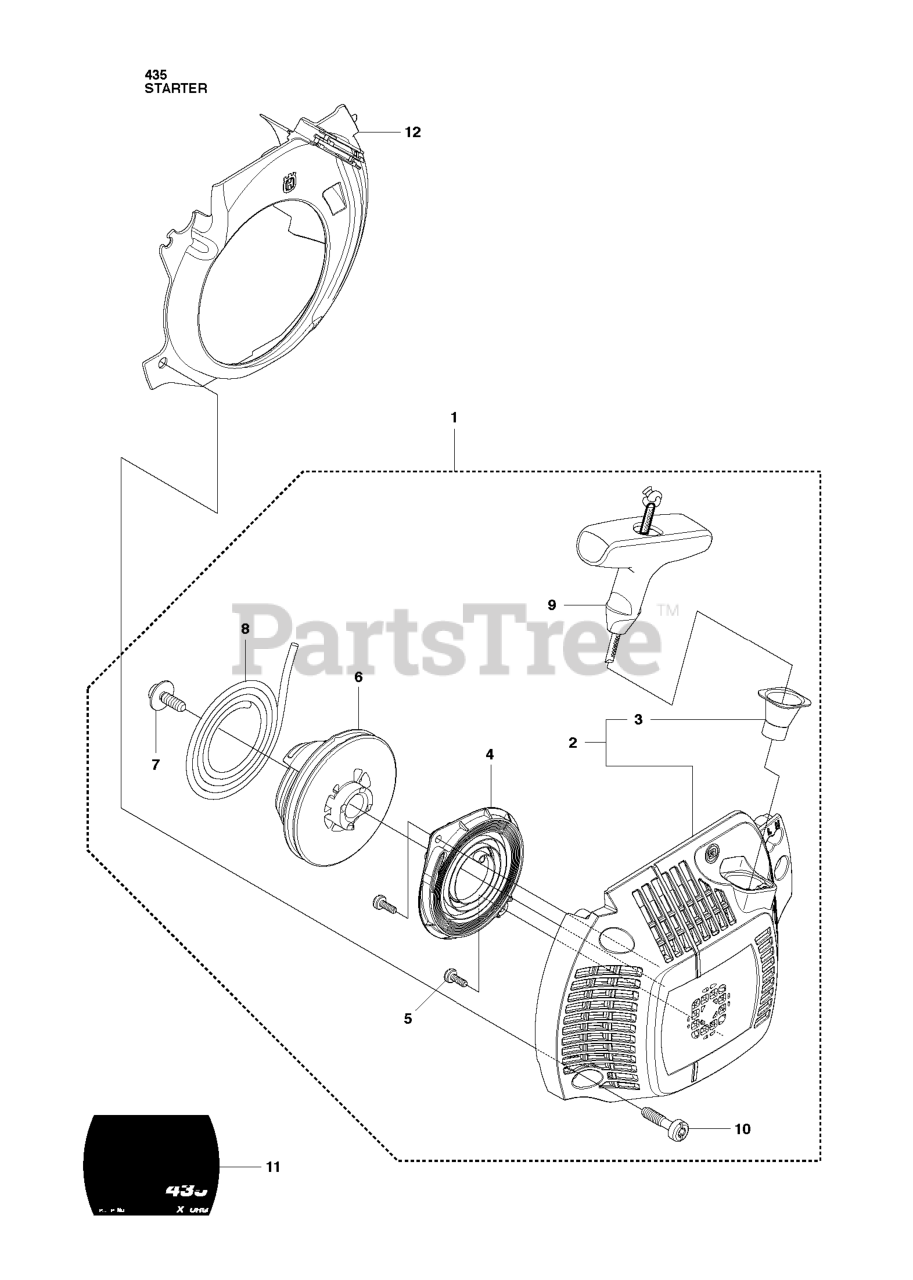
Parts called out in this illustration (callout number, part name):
1	STARTER ASSY
2	HOUSING STARTER
4	SPRING CASSETTE ASSY
6	STARTER PULLEY
8	STARTER ROPE
12	%COOLING AIR CONDUCTOR
